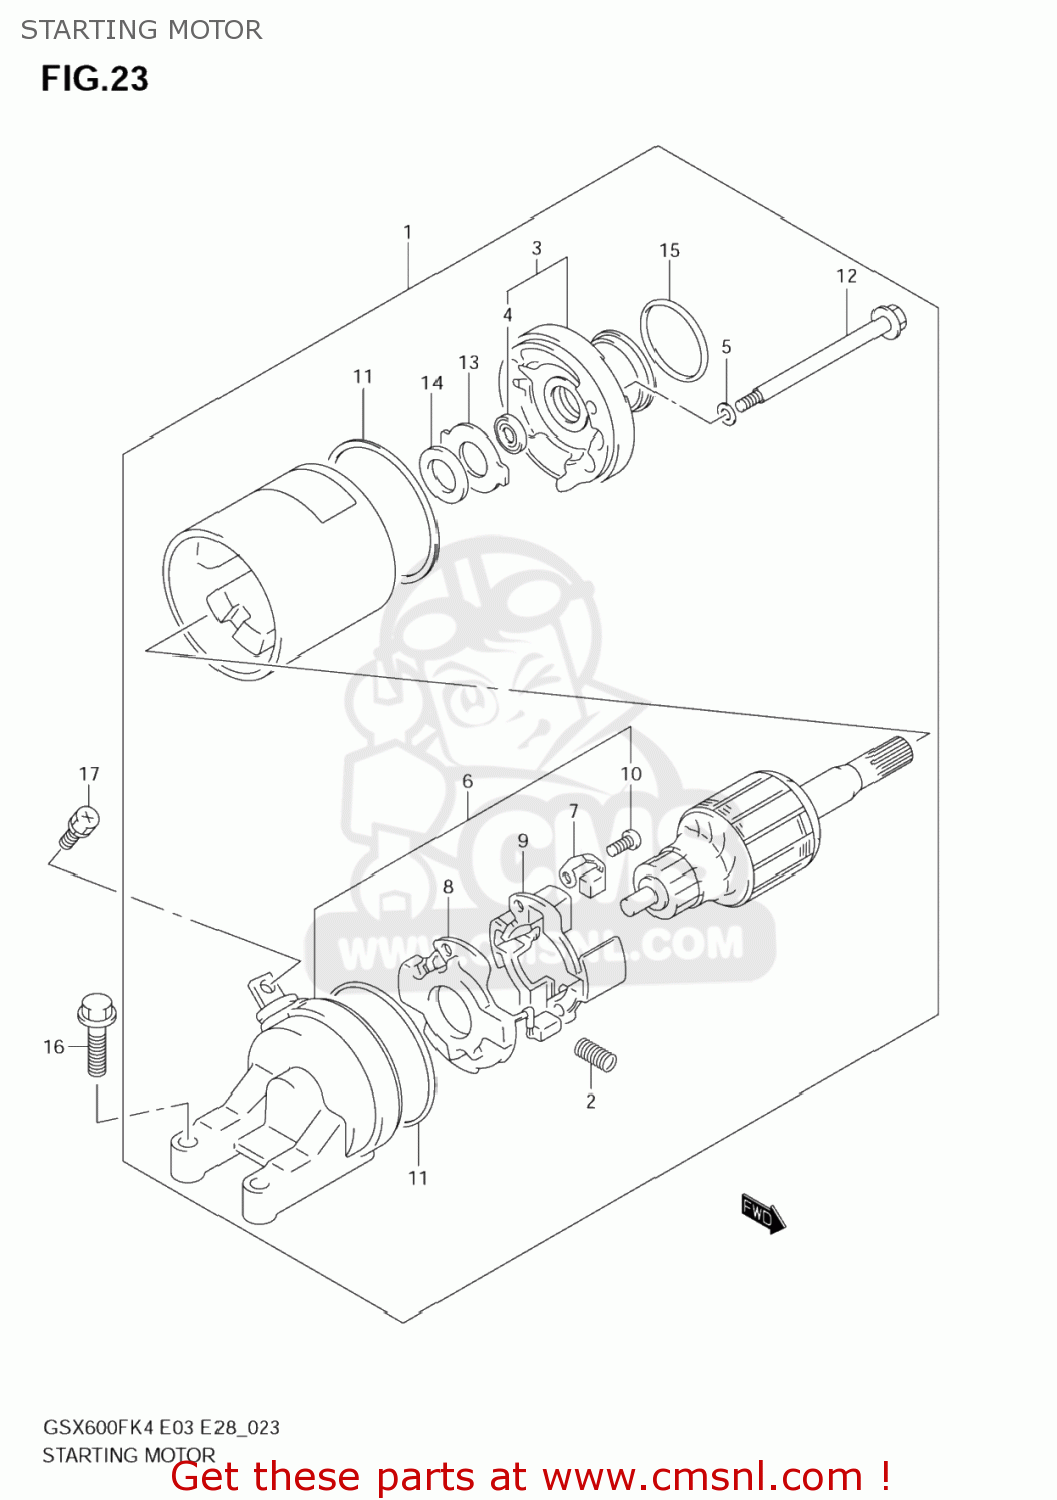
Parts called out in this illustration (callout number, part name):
1	MOTOR ASSY,STARTING
2	SPRING
3	BRACKET
4	SEAL,OIL
5	O RING
6	FRAME ASSY,COMMUTATOR
7	BRUSH
8	BRUSH SUB ASSY,STARTER
9	HOLDER,BRUSH
10	SCREW
11	O RING
12	BOLT
13	PLATE,LOCK
14	SHIM
15	O RING(D:3,ID:24.5)
16	SCREW (6X25)
17	SCREW(5X8)
